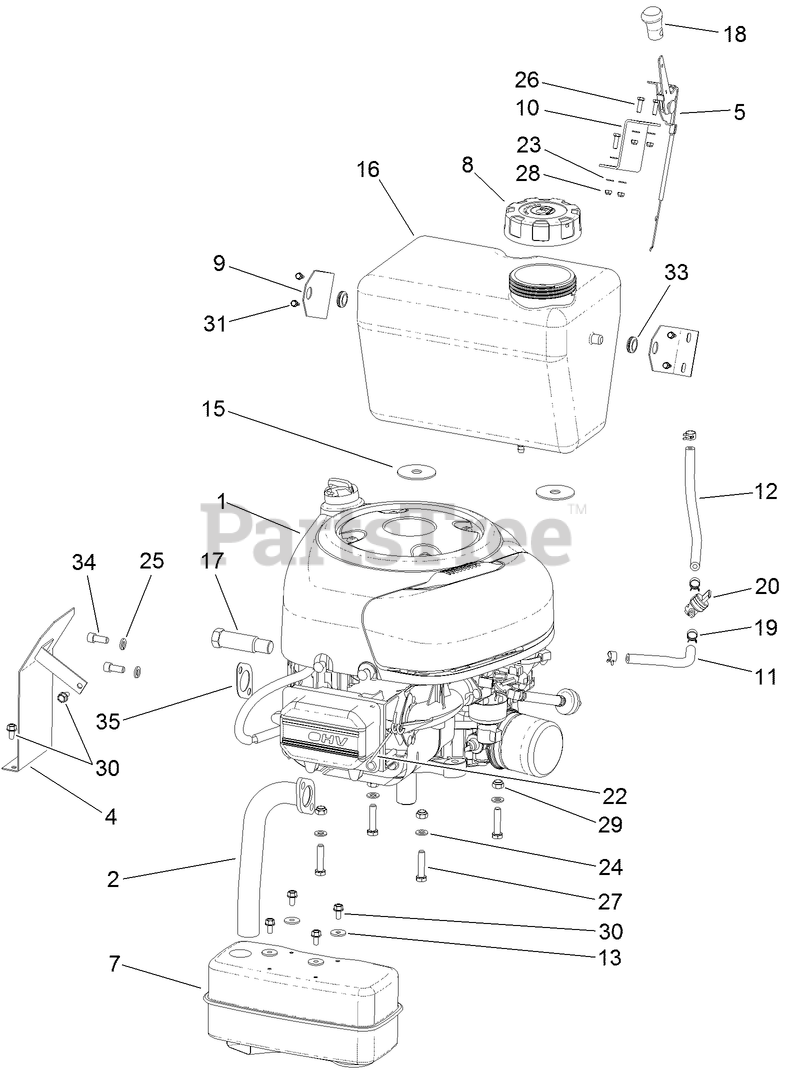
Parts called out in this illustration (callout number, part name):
2	TUBE-EXHAUST
4	COVER-EXHAUST
5	CABLE-THROTTLE/CHOKE
7	MUFFLER
8	CAP-FUEL
9	BRACKET-FUEL, TANK
10	HOLDER
11	LINE-FUEL
12	LINE-FUEL
13	WASHER-MUFFLER
15	WASHER-RUBBER
16	TANK-FUEL
17	COUPLER-DRAIN, OIL
18	KNOB-THROTTLE/CHOKE
19	CLAMP-LINE, FUEL
20	VALVE-TANK, FUEL
22	HOLDER-HARNESS, WIRING
23	WASHER
24	WASHER-PLAIN
25	WASHER-SPRING
27	SCREW-HH
28	NUT-LOCK
29	NUT-LOCK, NI
30	SCREW-HH
31	SCREW-TAP
33	BUSHING
34	SCREW-HH
35	GASKET
